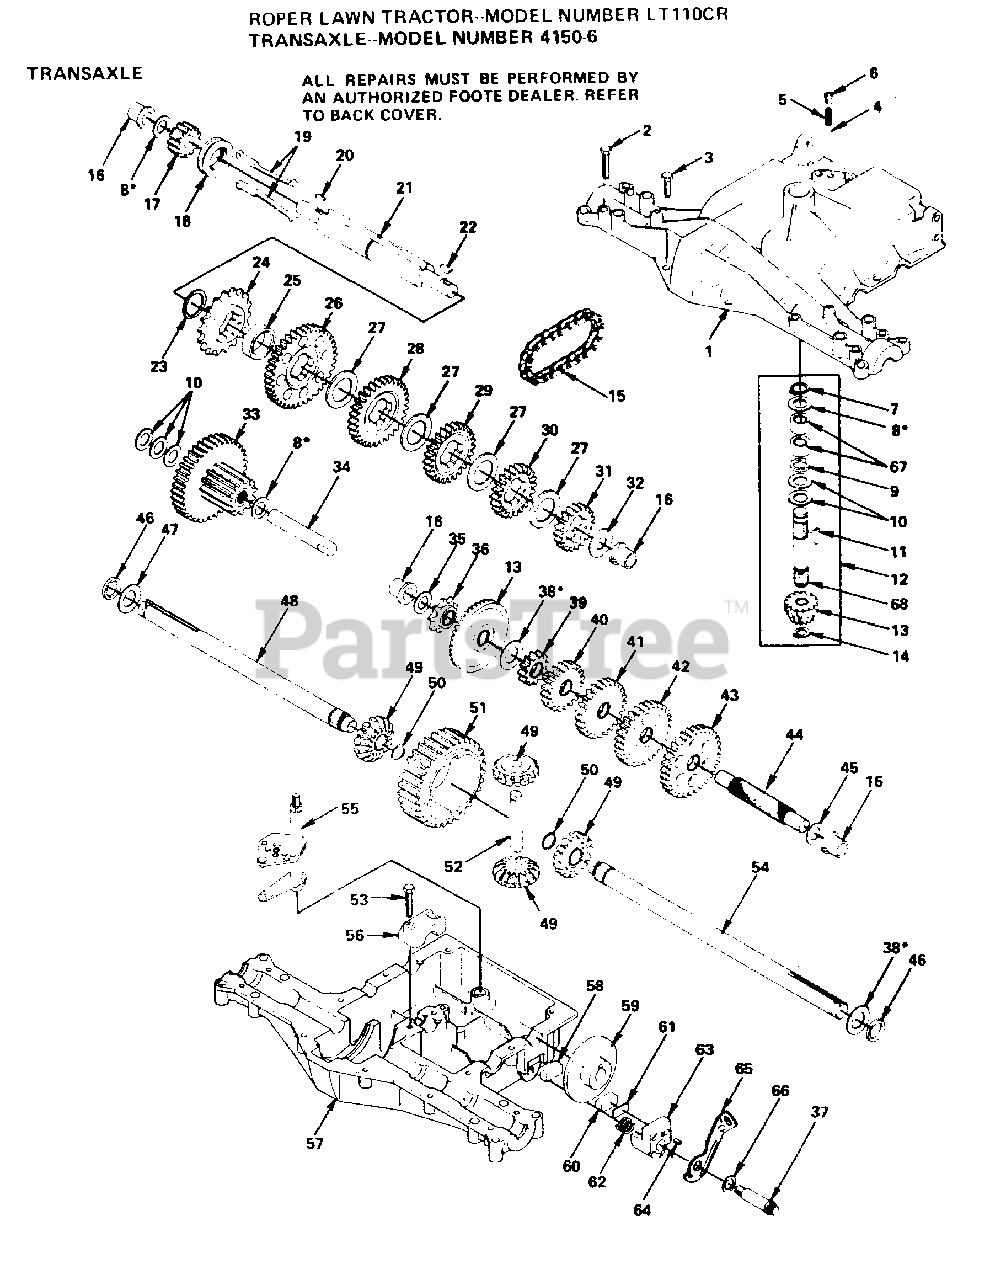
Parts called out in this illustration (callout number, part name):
1	HOUSING, UPPER
2	SCREW 1/4-20 X 1.31
3	SCREW 1/4-20 X .875
4	BALL DETENT
5	SPRING, DETENT
6	SCREW, SET
7	RING RETAINING
8	WASHER PLAIN
8	WASHER, PLAIN .632 X 1.00 X .026
8	WASHER, PLAIN .632 X 1.00 X .060
10	WASHER PLAIN
11	KEY WOODRUFF #9
12	ASSY, KIT, INPUT SHAFT & BEVEL GEAR
13	ASSY, KIT, PINION & BEVEL GEAR
14	RING, RETAINING
15	CHAIN, 24 PITCHES
16	BEARING, FLANGE
17	GEAR, SPUR 14T
18	COLLAR CLUTCH
19	KEY, CLUTCH
20	KEY WOODRUFF #3
21	SHAFT, INTERMEDIATE
22	KEY, WOODRUFF, #61
23	RING, RETAINING
24	SPROCKET, 18T
26	GEAR, SPUR, 37T
27	No Desciption for Part
28	GEAR, SPUR, 30T
29	GEAR, SPUR, 25T
30	GEAR SPUR, 22T
31	GEAR, SPUR, 19T
32	WASHER, PLAIN .640 X 1.37 X .061
33	ASSY, GEAR
34	SHAFT, IDLER
35	WASHER PLAIN
36	SPROCKET, 9 TEETH
37	BOLT, SHOULDER
38	WASHER PLAIN
38	WASHER, PLAIN .758 X 1.25 X .031
39	GEAR, SPUR, 12 TEETH
40	GEAR, SPUR 20T
41	GEAR, SPUR, 25 TEETH
42	GEAR, SPUR 28T
43	GEAR, SPUR, 31 TEETH
44	SHAFT, DRIVE
45	WASHER, PLAIN .632 X 1.00 X .060
47	WASHER, PLAIN .758 X 1.25 X .031
50	RING, RETAINING
51	GEAR, SPUR, 32T
52	SHAFT, CROSS
53	SCREW TAPPING
55	ASSY, SHIFTER
56	CAP, SUPPORT
57	HOUSING, LOWER
58	PUCK, FRICTION
59	DISC, BRAKE
60	PUCK, FRICTION
62	SPRING, COMPRESSION
63	SPRING, COMPRESSION
65	ASSY, LEVER, ACTUATING
66	WASHER, PLAIN
67	BEARING, NEEDLE
